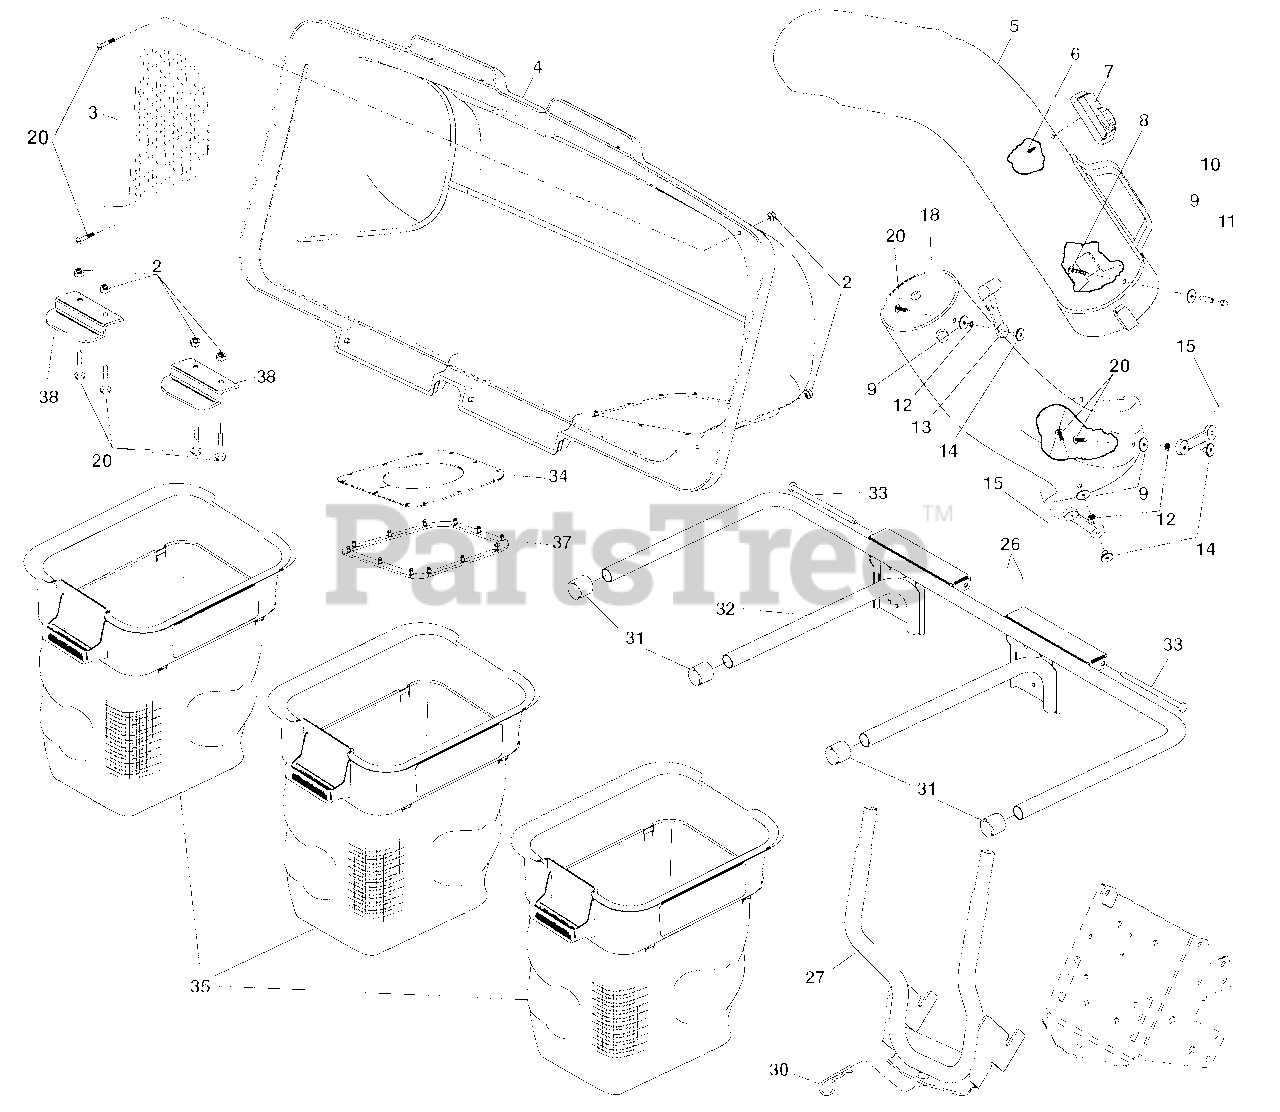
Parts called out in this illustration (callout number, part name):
2	Nut, Crown Lock #10-24
3	Screen, Cover
4	Cover Assembly
5	Chute, Upper
6	Screw, Special #10-14 X 1/2
7	Full Bag Indicator
8	Screw, #10-24 X 1-1/8
9	Washer 3/16 X 3/4 X 16 Ga.
10	Spacer, Split
11	Nut, Acorn #10-24
12	Washer, Lock
13	Latch, Chute
14	Nut, Weld
15	Latch
18	Chute, Lower
20	Screw #10-24 X 5/8
26	Spring, Retainer
27	Support Assembly
30	Spring, Retainer
31	Plug, Tubing End
32	Bagger, Frame
33	Pin, Hinge
34	Gasket, Cover
37	Seal, Cover
38	Latch Handle, Cover
